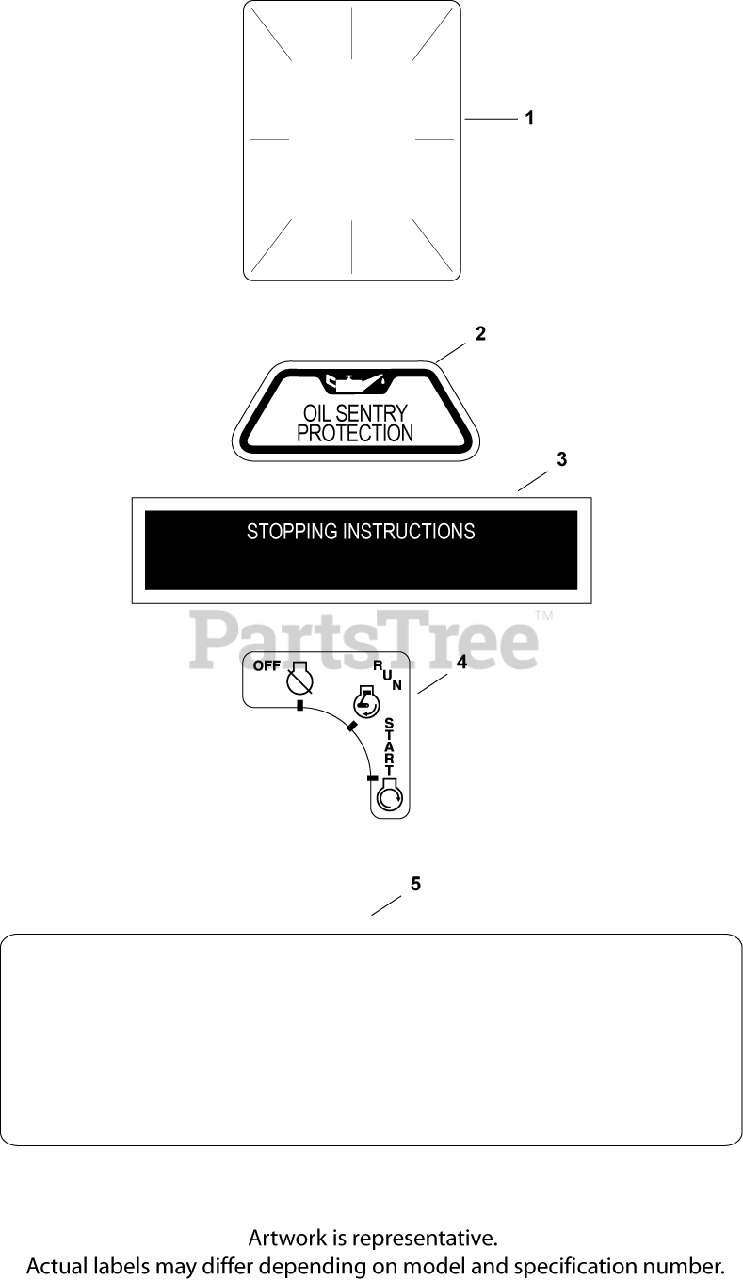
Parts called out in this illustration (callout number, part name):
1	DECAL, CLEAR LAMINATE USE 25 113 70-S
2	DECAL, OIL SENTRY - (#DSC)
3	DECAL, STOPPING INSTRUCTION
4	DECAL, KEY SWITCH
5	DECAL, 18 HP
